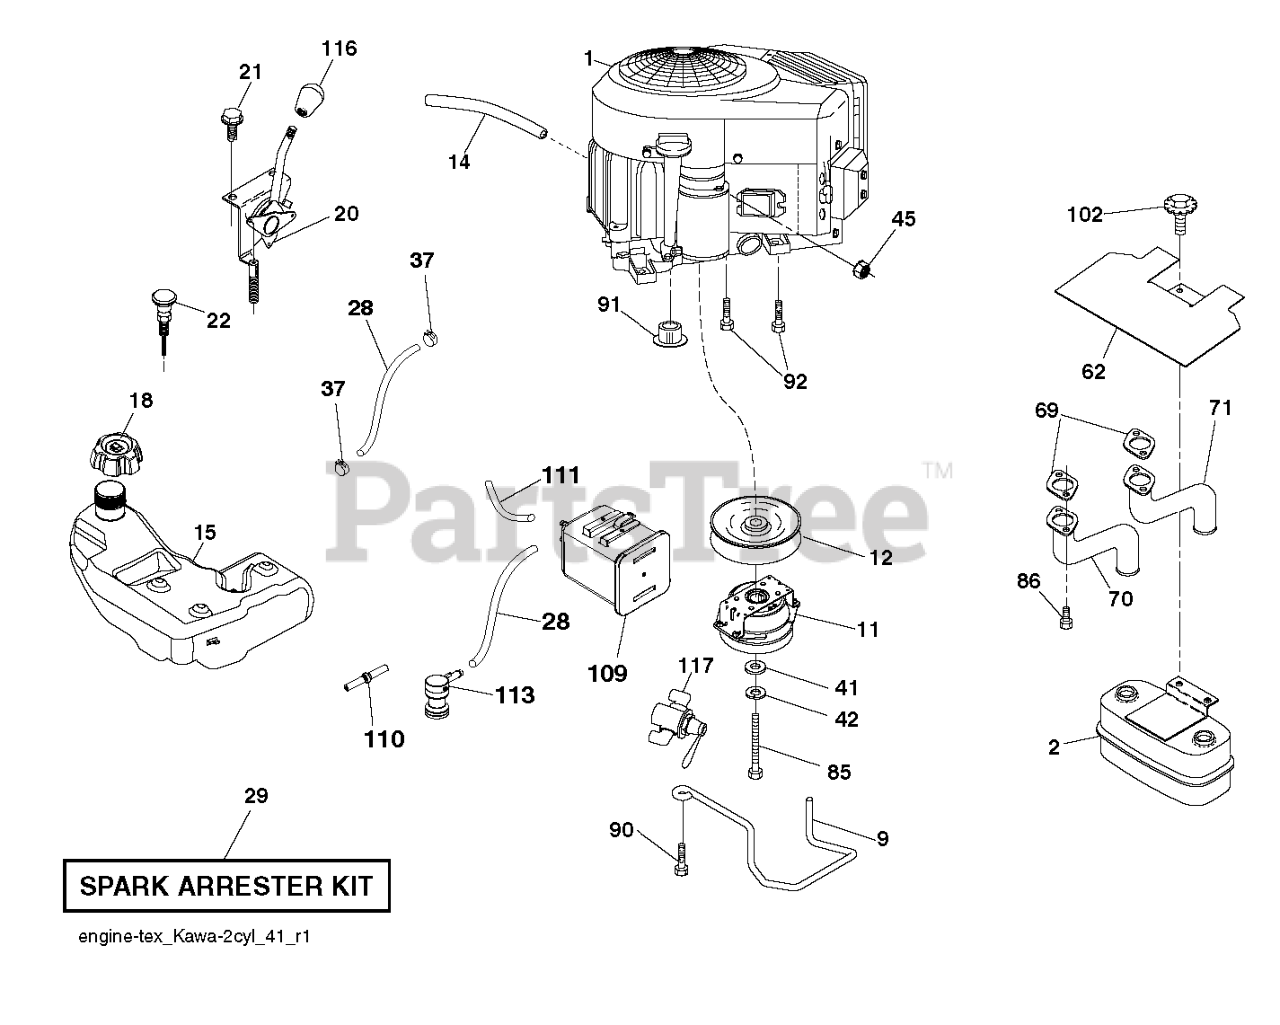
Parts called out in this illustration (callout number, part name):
2	MUFFLER.ASM.TWN.EXTNDED.DFLCTR
9	KEEPER.BELT.ENGINE.4.2
11	CLUTCH.ELECTRIC.LT.48"*
12	PULLEY.ENGINE.TUFFTORQ
14	TUBE, DRAIN OIL ASM.
15	RP_TANK.ASSY.4.GAL.2.PORT.EPA
18	CAP.ASM.FL.RITCH.3"E10.SYM.498
20	CONTROL.THROTTLE.PRO.
21	SCREW.#10 X 0.750.BOS
22	CONTROL.CHOKE.ERGO.PUSH-IN.BLA
28	LINE.FUEL.64"REAR.EMIS
29	KIT.SPARK ARRESTOR 794945 B&S
37	HOSE CLAMP
42	LOCKWASHER
45	NUT
62	SHIELD.HEAT.MUFFLER
70	TUBE.EXHAUST.LH.FR961/FR730
71	TUBE.EXHAUST.RH.FR961/FR730
85	BOLT HEX 7/16-20X4-1/4"
86	NUT.HEX.FLANGE.TOPLOCK
87	BOLT 5/1618UNC X 3/4 W/ SEMS
90	SCREW 3/8-16X1
91	BUSHING.1.375OD
92	SCREW 3/8-16X1
109	CANNISTER, CARBON
110	VALVE.ASM.ANTI-SLOSH
111	PURGE.LINE.36"REAR.CALIFORNIA
113	VALVE.SLANT.CARTRDG.90 DEG.TEX
116	KNOB - SHIFT
117	VALVE FUEL RESERVE
